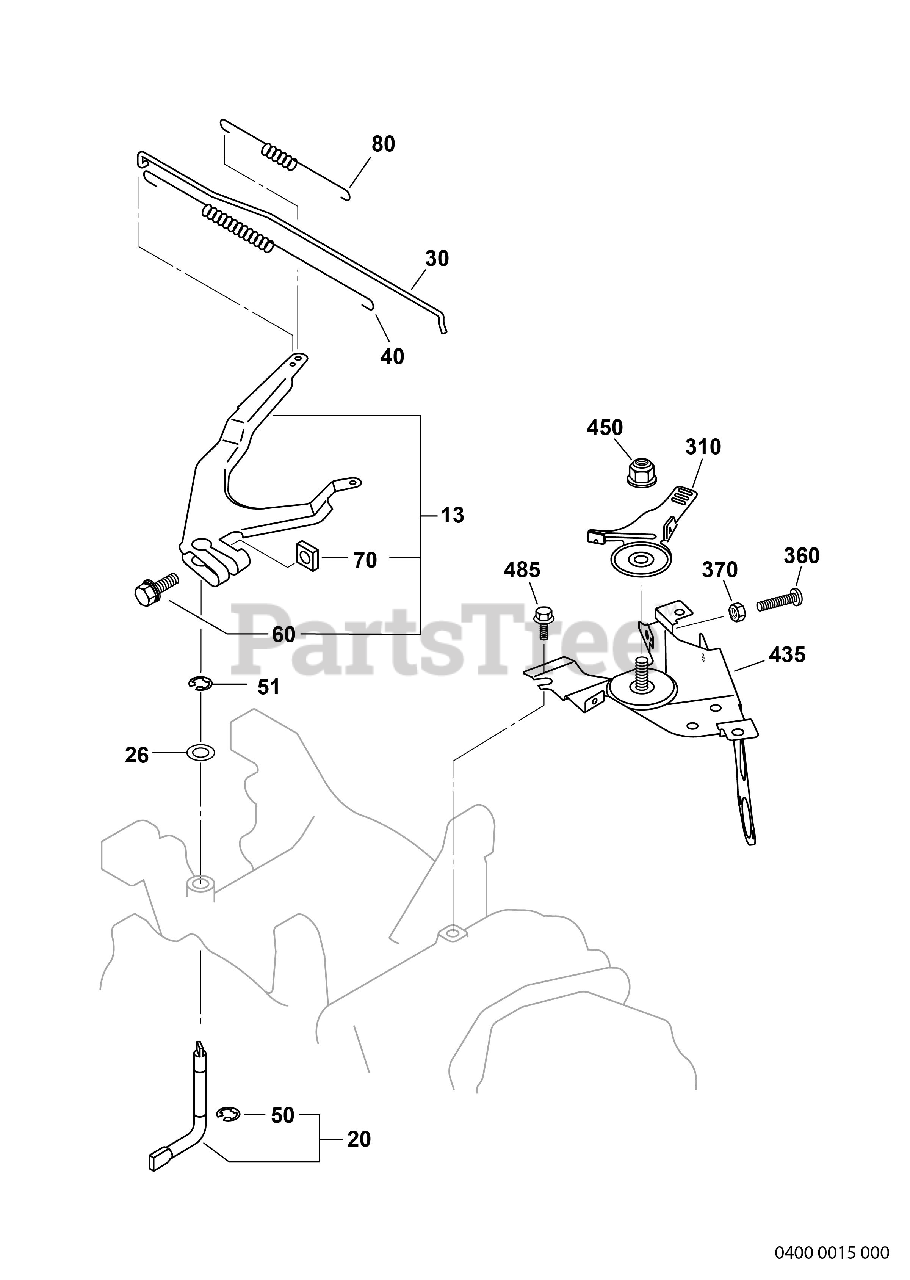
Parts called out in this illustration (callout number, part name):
13	GOVERNOR LEVER AY
20	GOVERNOR SHAFT CP
30	GOVERNOR ROD
60	BOLT AND WASHER AY
80	GOVERNOR SPRING
310	SPEED CONTROL LEVER
435	SPEED CONTROL BKT CP
